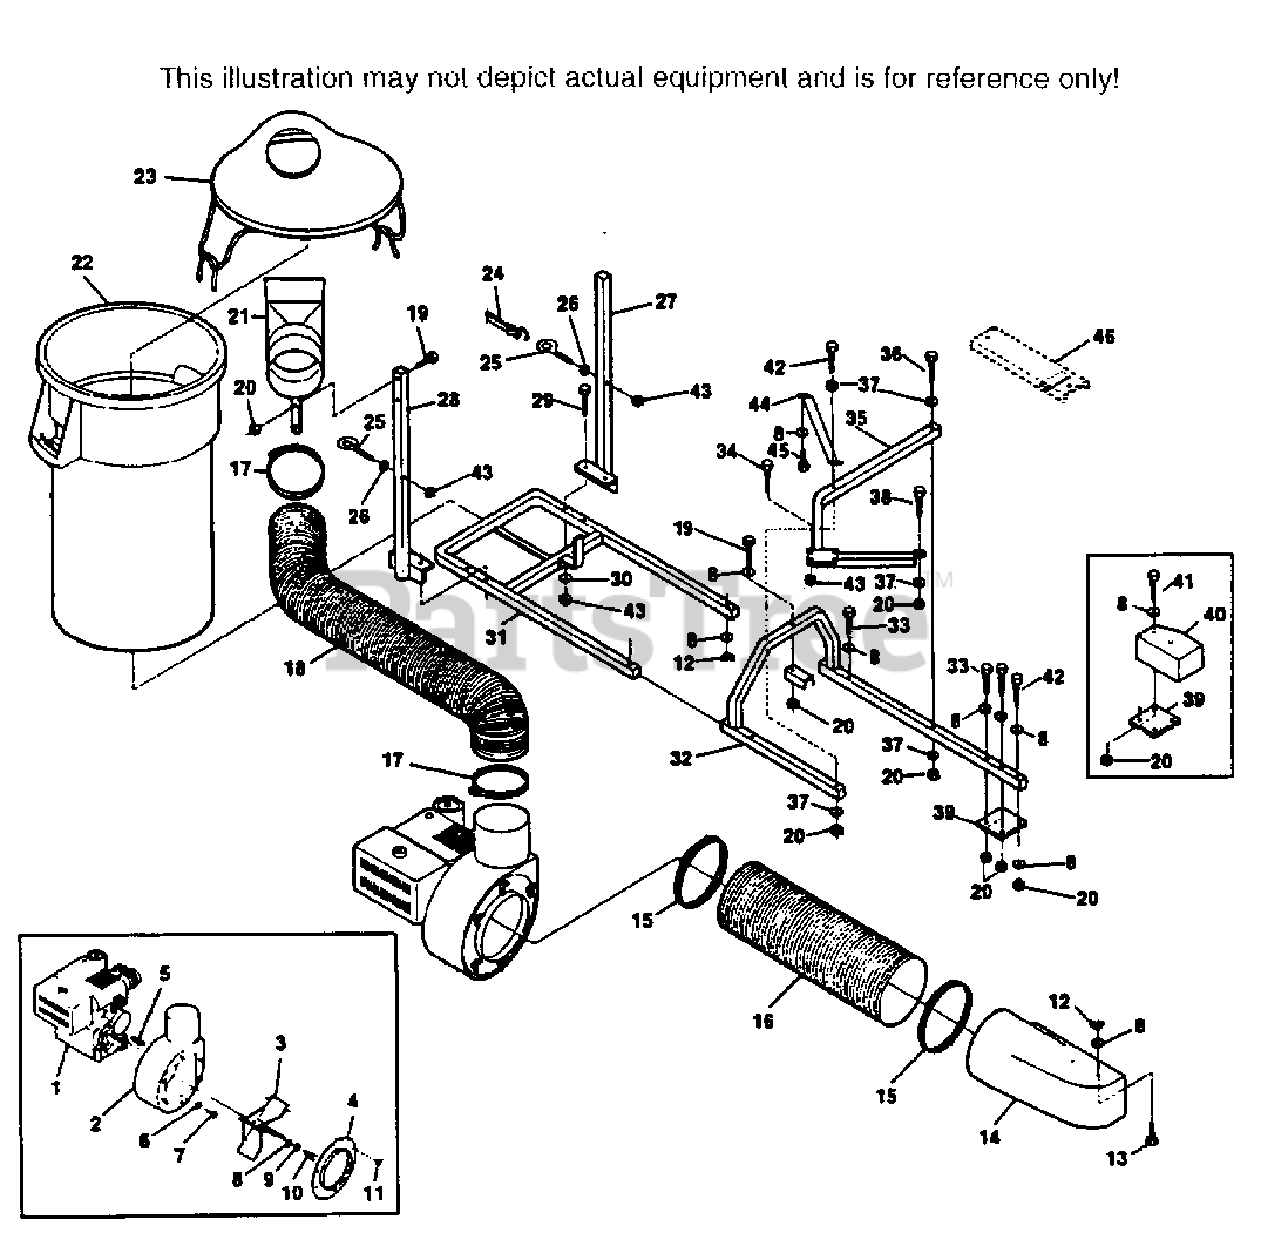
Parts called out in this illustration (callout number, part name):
1	ENGINE, 5 HP I.C.(1" CRANKSHAFT)
2	BLOWER HOUSING ASSEMBLY
3	FAN ASSEMBLY(1" BORE)
4	INLET ADAPTOR
5	KEY 1/4 X 1/4 X 1-1/2"(FOR 1" CRANKSHAFT
5	KEY AND BUSHING KIT(USED ON 3/4" CRANKSHAFT)
7	BOLT, 5/16-24 X 1"
8	WASHER, 3/8 15/16 X 25/64 X 12GA
11	WING NUT, 5/16-18
12	WING NUT, 3/8-16
14	BOOT
15	CLAMP 8"
16	HOSE 8"
17	CLAMP 6"
18	HOSE 6"
20	NUT, 3/8-16 ELASTIC STOP
21	HOSE SUPPORT
22	BUCKET
23	BUCKET COVER
24	RUBBER STRAP
25	EYEBOLT, 5/16-18 X 2-3/4"
27	BUCKET BRACE-LH
28	BUCKET BRACE-RH
31	BUCKET SUPPORT FRAME
32	MAIN FRAME
35	ENGINE MOUNTING FRAME
37	WASHER, 3/8 X 1-1/2 X 7 GA.
39	BALLAST SUPPORT
40	BALLAST
43	NUT, 5/16-18 ELASTIC STOP
44	ENGINE FRAME BRACE
46	FRAME EXTENSION
